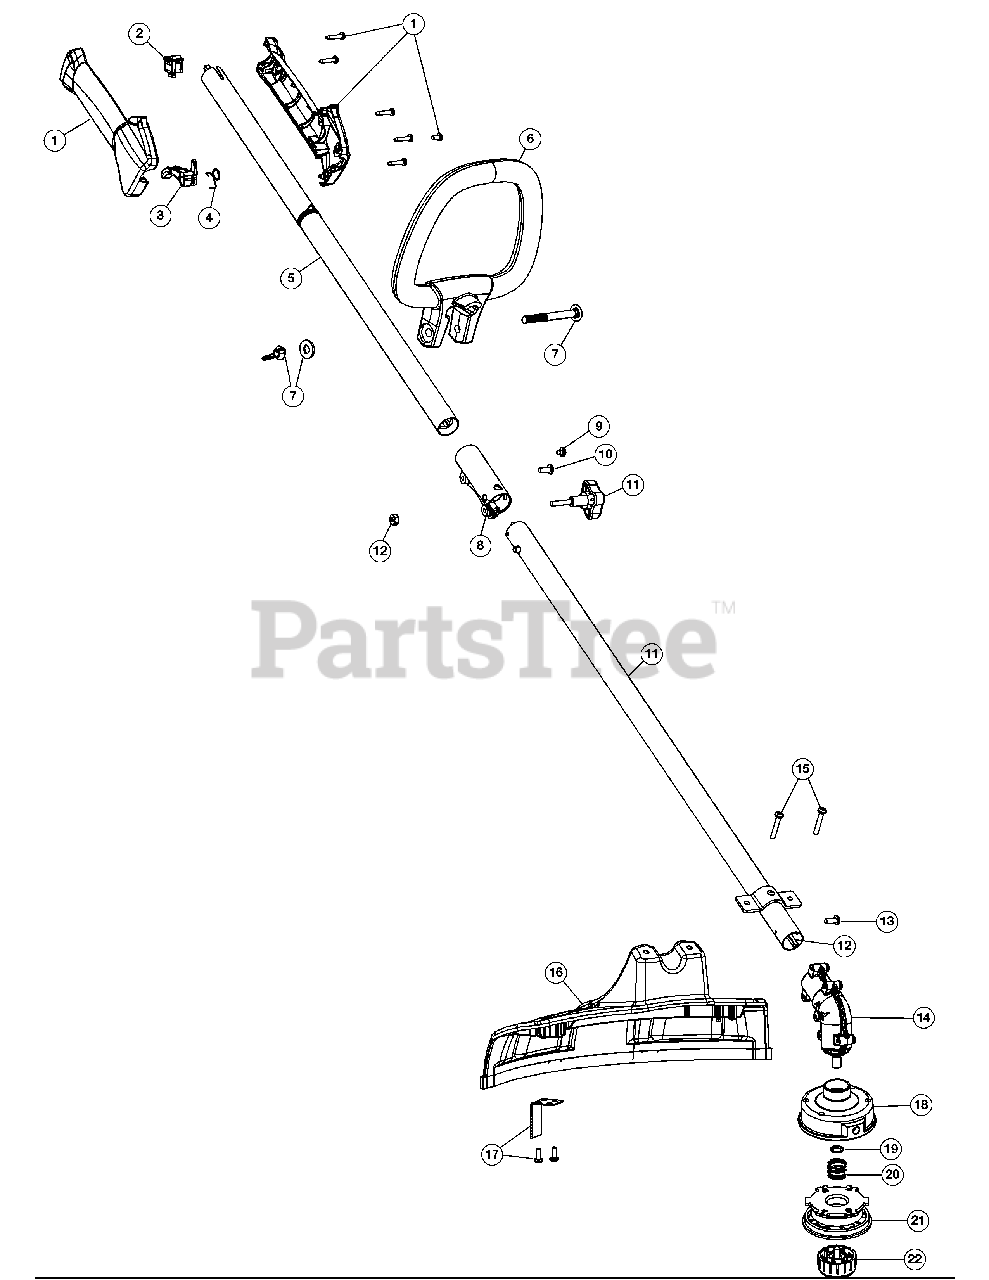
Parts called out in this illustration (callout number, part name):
1	Throttle Housing Assembly (Incl. 2 - 4)
2	Throttle Trigger
3	Throttle Trigger Spring
5	Upper Drive Shaft Housing Assembly
6	D-Handle (Incl. 7)
7	D-Handle Hardware Assembly
8	Split Boom Coupler (Incl. 9 - 10)
11	Lower Drive Shaft Housing Assembly (Incl. 12)
12	Lower Flexible Drive Shaft
13	Anti-Rotation Screw
14	Gear Box Assembly (Incl. 13 & 18 - 22)
15	Shield Mounting Screws
16	Shield Assembly (Incl. 17)
17	Blade Assembly
18	Outer Spool Assembly (Incl. 19)
19	Retainer
21	Inner Reel
22	Bump Knob Assembly
